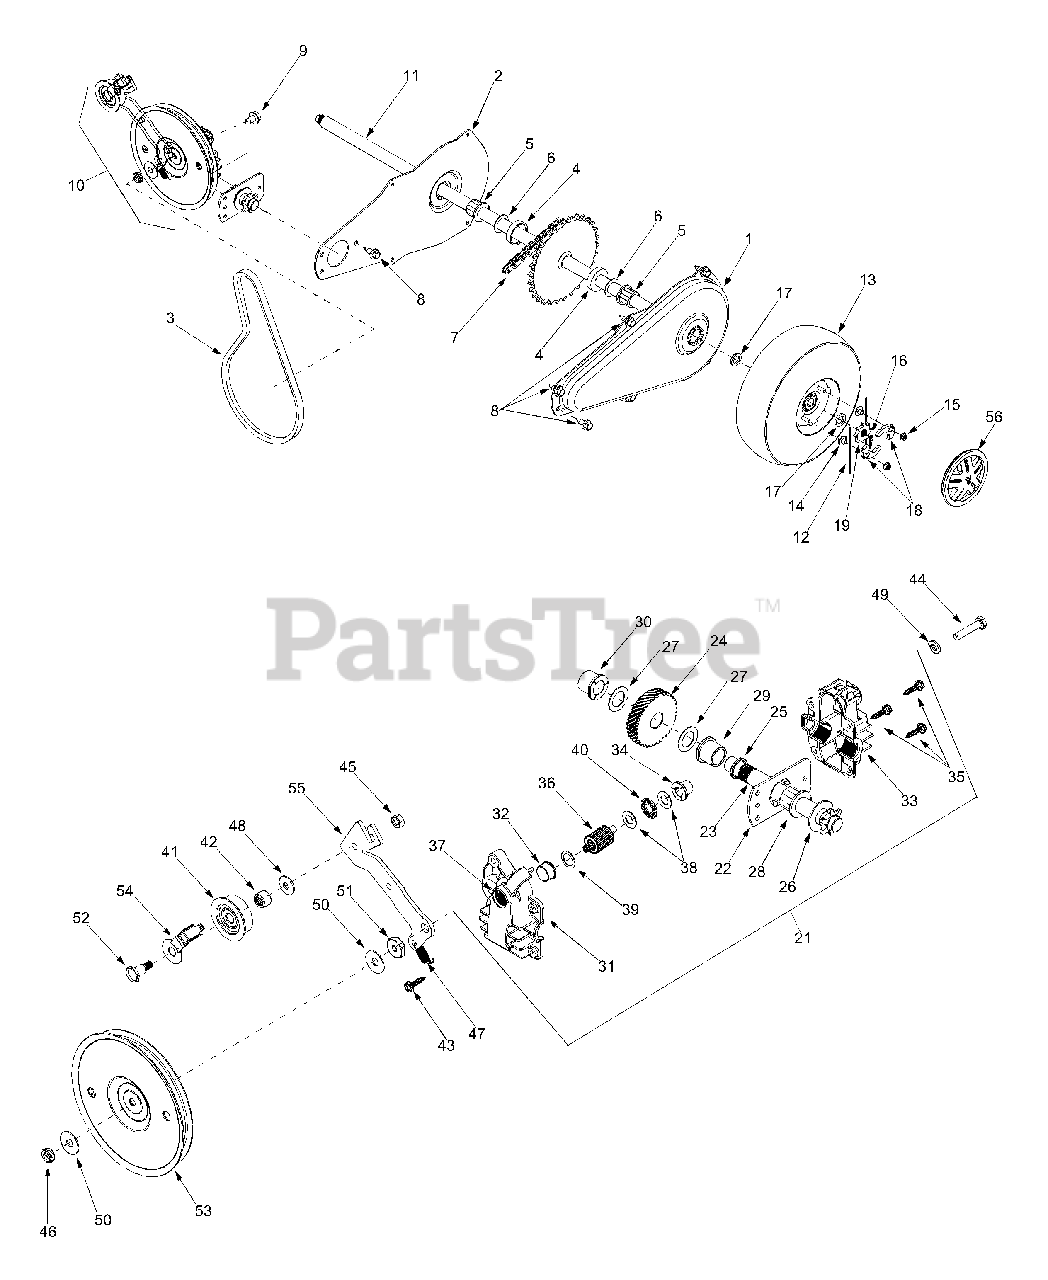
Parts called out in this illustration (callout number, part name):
3	V-Belt
4	Spacer
5	Hex Flange Bearing
6	Flat Washer
7	Chain
8	Self Tapp. Screw 1/4-20
9	Hex Washer Screw 5/16
10	Chipper Shredder Trans. Assembly
11	Axle Shaft Assembly
12	Plastic Spring Ratchet
13	Wheel Complete 10 x 4 x 4
14	Hex Nut 1/4-20
15	Hex Flanged Lock Nut 1/4-20
16	Cotter Pin
17	Flat Washer 5/8 ID x 1.0 OD
18	Pawl LH .345 ID
19	Wheel Ratchet 1.62 OD x .5 serr
21	6T Shredder Transmission Assy.
23	6T Sprocket Output Shaft
24	Helical 34T Gear
25	Oil Seal
26	Flat Washer .64 ID x 1.24 OD
27	Flat Washer 5/8 x 1.0
28	H ex Flange Bearing .631 ID
29	Flange Bearing .629 ID
30	Flange Bearing .566 ID
31	Lower Housing
32	Flange Bearing .503 ID
33	Upper Housing
34	Flange Bearing .378 ID
35	Hex Washer Screw #10-16 x .75
36	Pinion Shaft 10T
37	Oil Seal
38	Thrust Washer .382 ID x .684 OD
39	Flat Washer .504 ID x .70 OD
40	Thrust Bearing .375 ID x .812 OD
41	Idler Pulley Assy. w/ Bearing
42	Needle Bearing .375 ID x .375 OD
43	Hex Screw #10-16 x .75
44	Hex Cap Screw 1/4-20 x 1.25
45	Hex Nut 1/4-28
46	Hex Jam Nut 5/16-24 LH Thd
47	Extension Spring 1.12 Lg
48	Bell Washer .265 ID x .75 OD
49	Lock Washer 1/4
50	Bell Washer .325 ID x .930 OD
51	Shoulder Spacer .375 ID x .165 OD
52	Shoulder Bolt 1/4-28 x .375
53	Flat Pulley 5.06 Dia
54	Belt Keeper
55	Idler Bracket Assembly
56	Hub Cap
